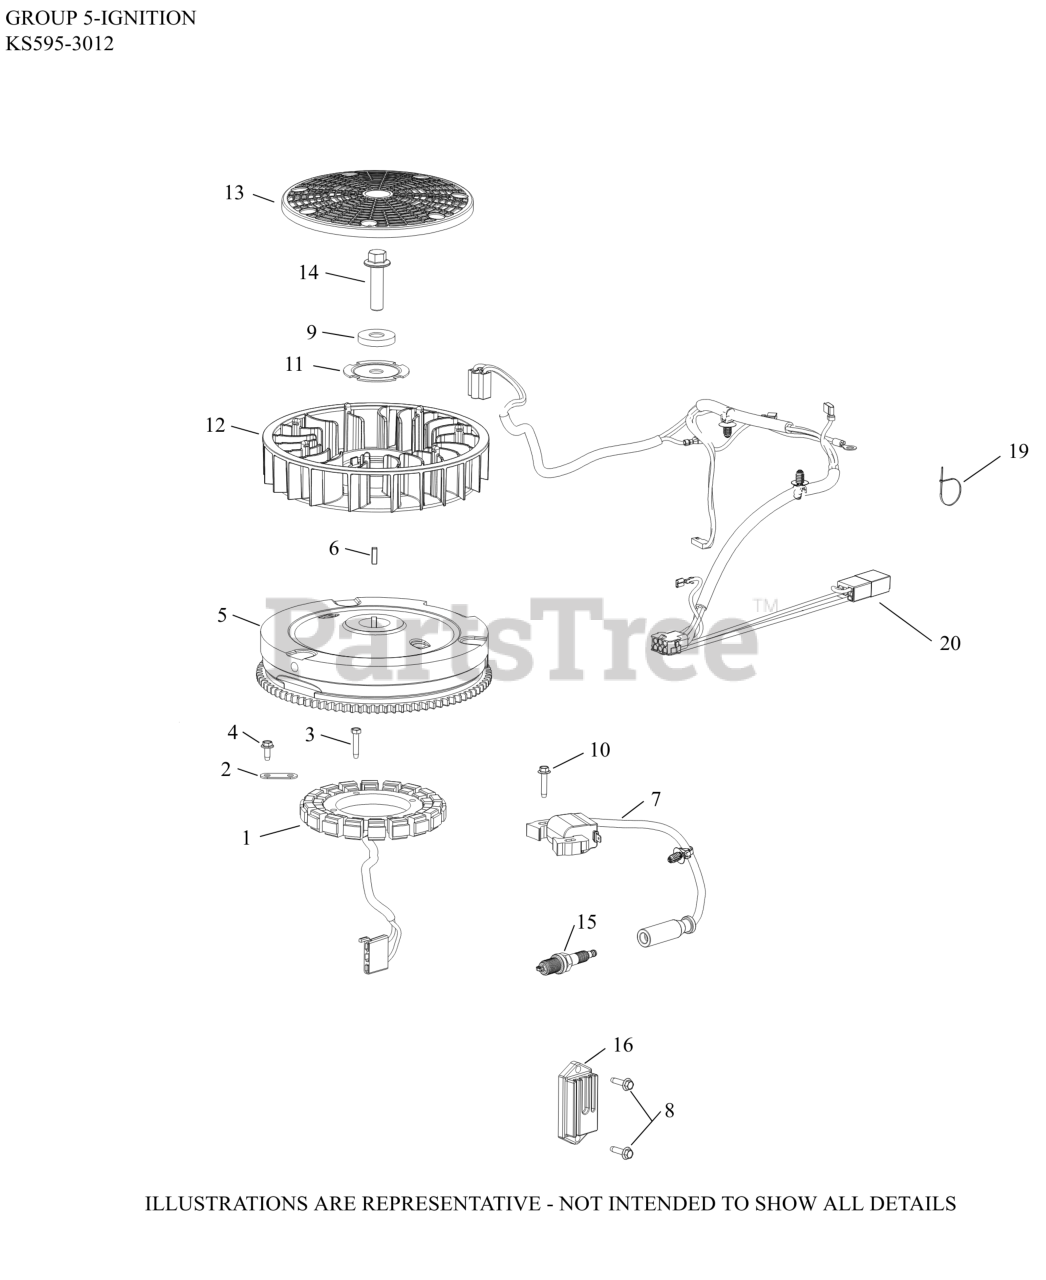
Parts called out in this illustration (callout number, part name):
1	STATOR ASSY, 12A
2	CLIP, STATOR WIRE
3	SCREW, THREAD FORMING
4	SCREW, FLG THD FRM M5X0.8X13
5	FLYWHEEL, ASSY
6	KEY, SQUARE
7	MODULE, INDUCTIVE IGNITION COIL
8	SCREW, THD FRM-USE 25 086 473-S
9	WASHER, FLAT
10	SCREW, THREAD FORMING
11	PLATE, FAN MOUNTING
13	SCREEN, GRASS
14	SCREW, HEX FLANGE
15	PLUG SPARK 12MM RFI
16	REGULATOR/RECTIFIER 12/15A HALF-WAVE STD
17	HARNESS, WIRING NON-OSU, NON MTD
